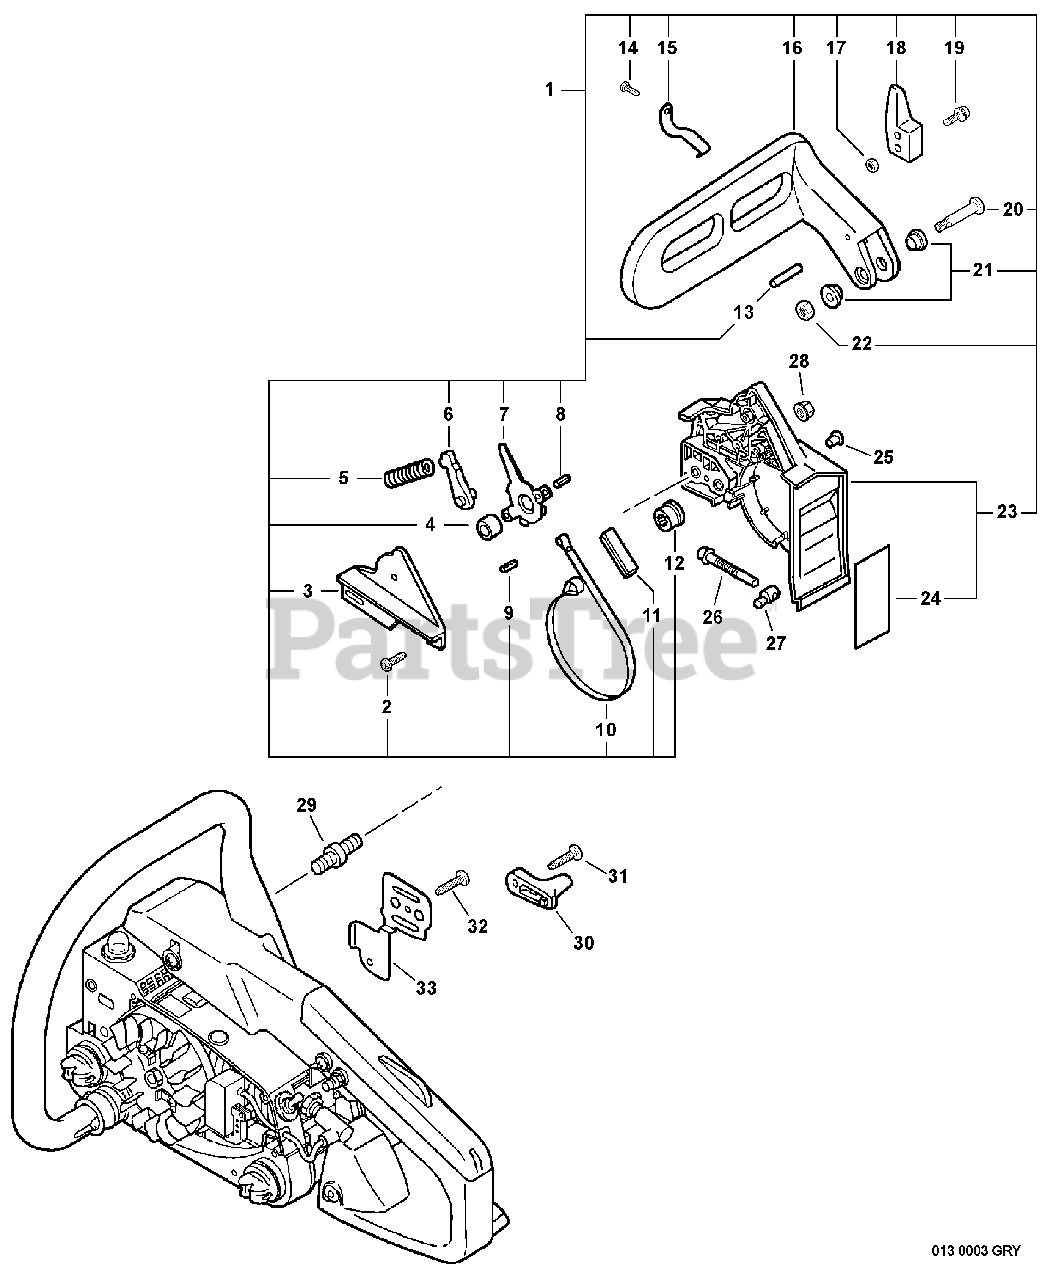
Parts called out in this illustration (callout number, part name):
1	CHAIN BRAKE ASSY
2	SCREW - 4X12 -- TAPPING
3	COVER, BRAKE - GRAY
4	SPACER - 8
5	SPRING, BRAKE
6	STOPPER, BRAKE
7	LEVER, BRAKE
8	PIN - SPRING -- 4X8
9	PIN - SPRING -- 2.5X12
10	BAND, BRAKE
12	ADJUSTER, BRAKE BAND
13	ROLLER - 4X23.8
14	SCREW - 4X10
15	SPRING, RETURN
16	LEVER, BRAKE - ORANGE
18	WEIGHT, BRAKE
19	SCREW - 4X22
20	SCREW - 5X32
22	LOCKNUT - 5
23	GUARD, SPROCKET - GRAY
24	DEFLECTOR, HEAT
26	SCREW, TENSIONER
27	TENSIONER, CHAIN
28	NUT - 6 -- FLANGE
29	STUD, GUIDE BAR
30	CATCHER, CHAIN
31	SCREW - 5X20 -- TAPPING
32	SCREW - 4X10
33	PLATE, GUIDE - OUTER
